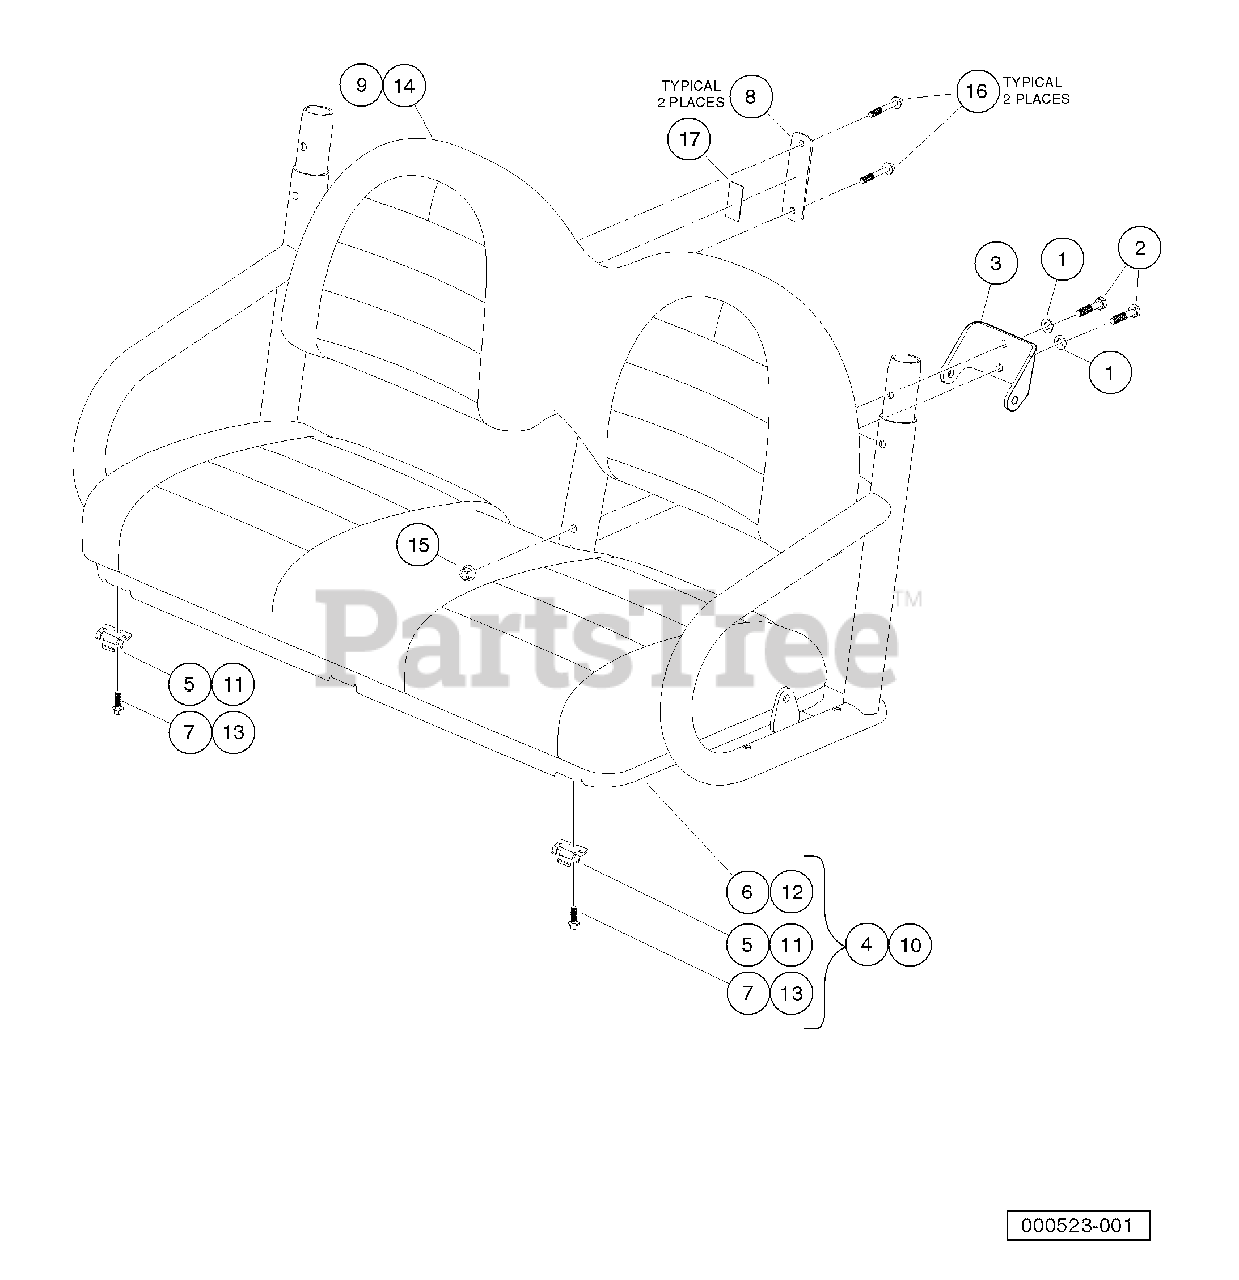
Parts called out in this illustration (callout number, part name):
1	Washer, Hard, M10, Zn-Ni/Blk
2	Bolt, M10 X 45, Zn-Ni
3	Bracket, Seat Belt, Bench
4	Asm, Seat Bottom, Bench, Gray
5	Hinge Plate
6	Asm, Seat Bottom, Bench
7	Bolt Flg Blk, M8 X 25, Loctite
8	Bracket, Seat Back, AWD
9	Seat Back, Bench, Gray
10	Asm, Seat Bottom, Bench, Black
11	Hinge Plate
12	Seat Bottom, Bench, Black
13	Bolt Flg Blk, M8 X 25, Loctite
14	Seat Back, Bench, Black
15	Nut, Flanged, M10 x 1.5, Black
16	Bolt Flg Blk, M8 X 55, Loctite
